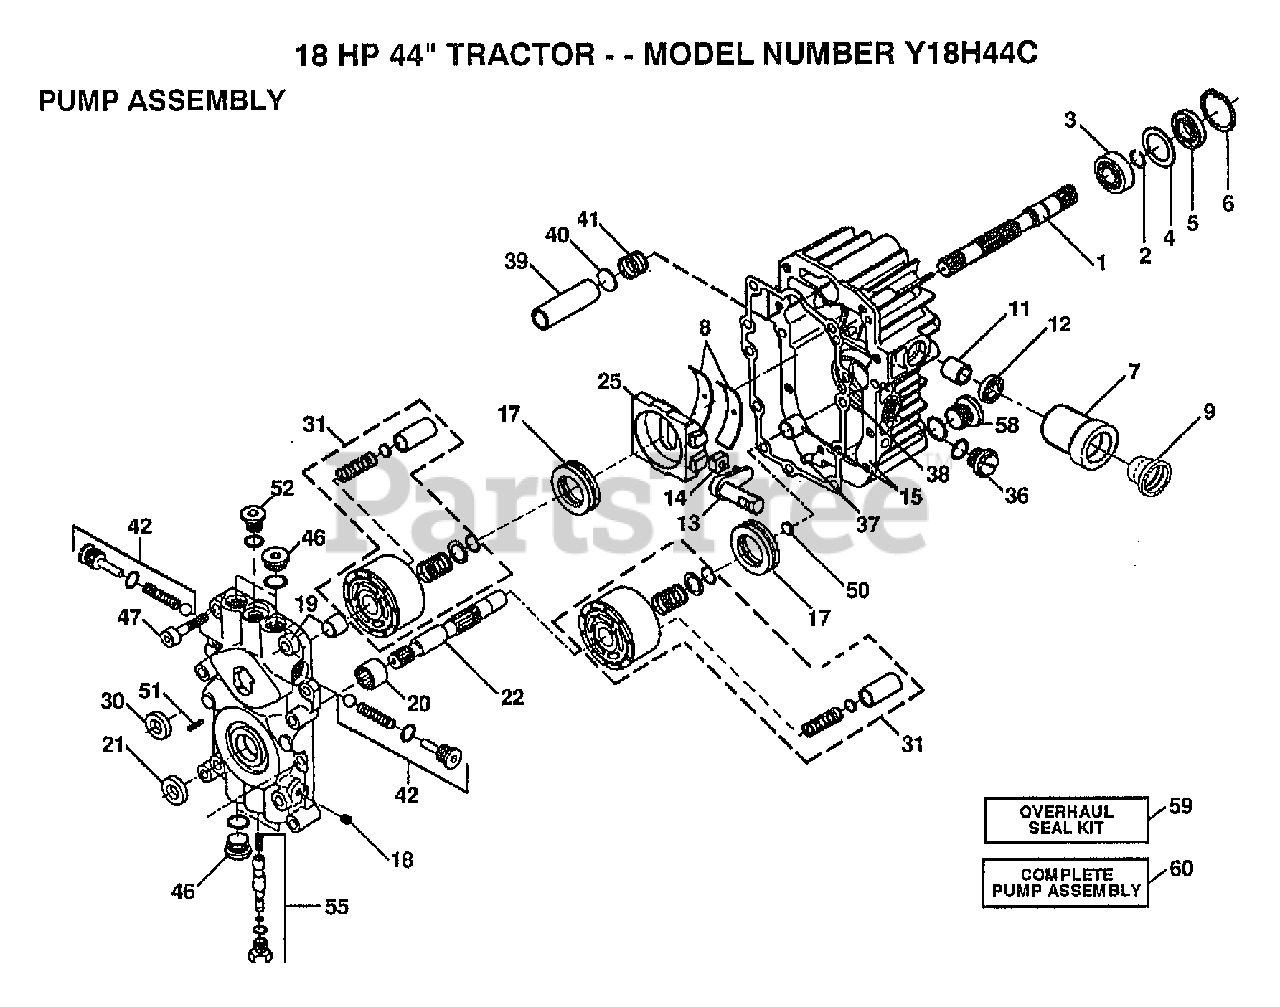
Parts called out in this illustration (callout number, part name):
1	SHAFT.PU.2003022
2	RETAINIANG RING-(2003016)
3	BALL BEARING
4	SPACER
5	SEAL LIP
6	RING.RET.2003052
7	PUMP.2003081.
8	CRADLE BEARING (2003023)
9	DIAPHRAGM.OIL.RES -2003084
11	BEARING
12	SEAL.9008000-0126
13	TRUNION ARM (2003005)
14	GUIDE.2000015.HYD
18	PLUG PIPE
19	"KIT,CTR SECTION (2513007)"
20	NEEDLE BEARING
21	LIP SEAL-9008000-0127
22	SHAFT
25	"SWASHPLATE,VARIAB"
30	SEAL LIP
31	"KIT,BLOCK CYLINDE"
36	"PLUG,PLASTIC 9005200-8700"
37	PIN
38	GASKET.20030600
39	FILTER
40	WASHER (2000011)
41	SPRING
42	KIT.VALVE.2513014
46	PLUG
47	SCREW9007314-0808
50	WASHER
51	PIN
52	PLUG
55	"KIT,BYPASS VALVE"
58	PLUG
59	"KIT,OVERHEAD SEAL -2513013"
60	PUMP.BDU-10S-114
